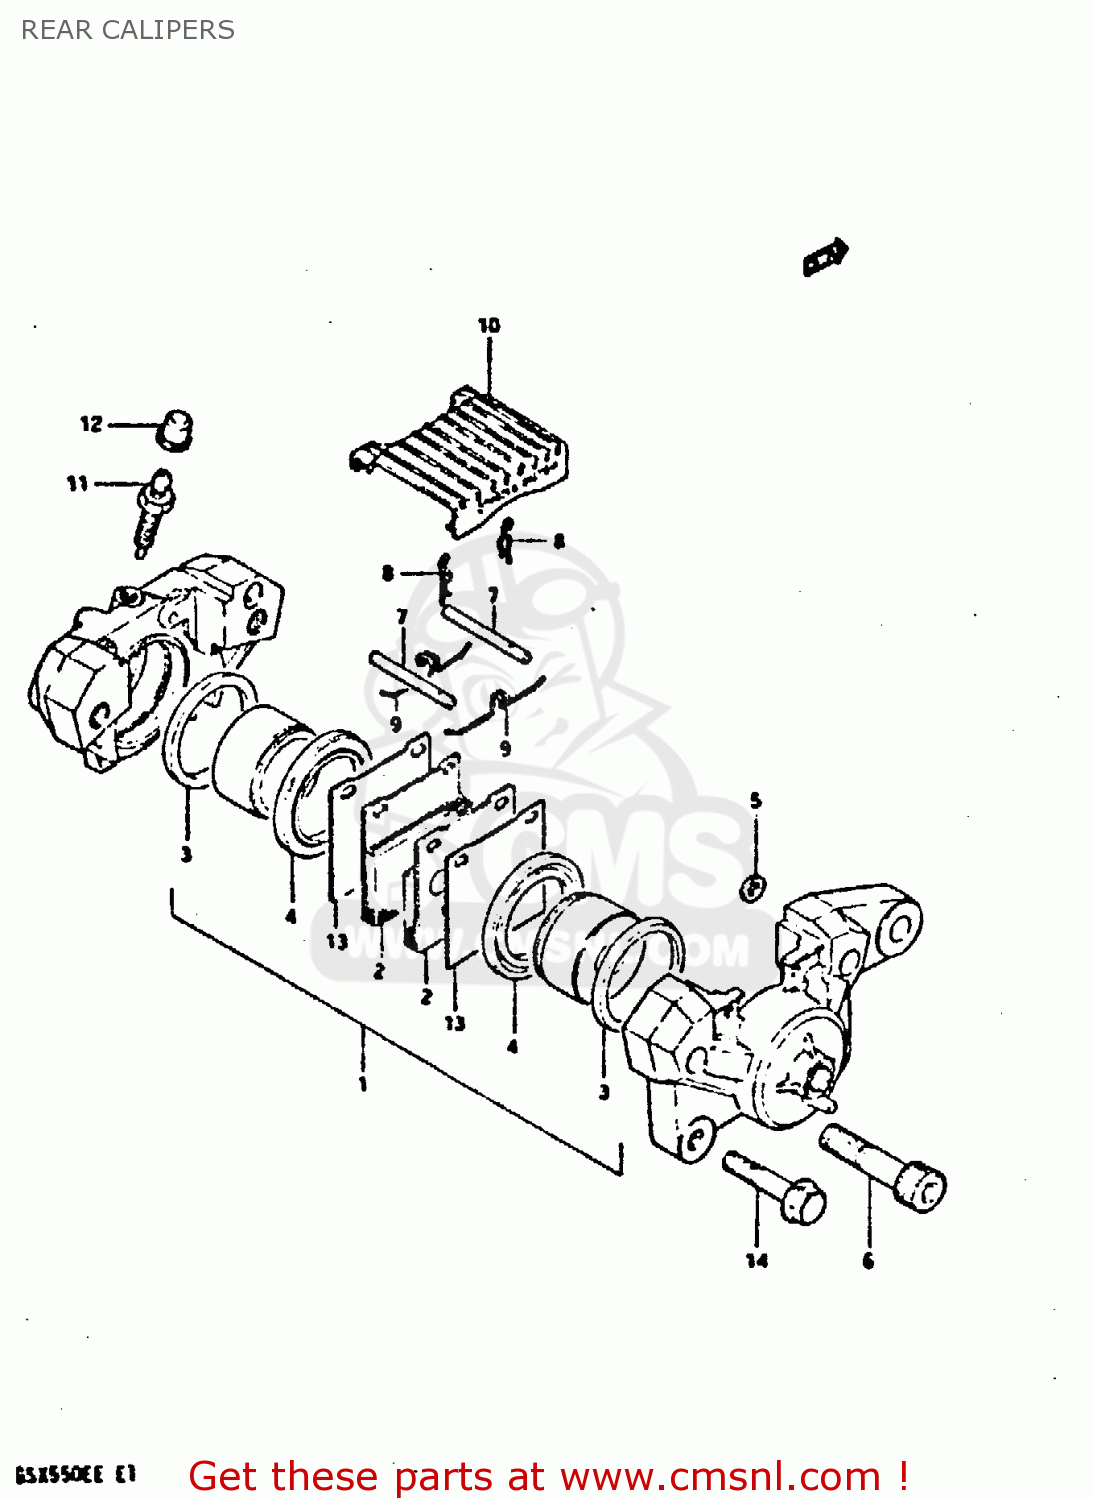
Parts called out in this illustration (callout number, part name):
1	PISTON SET
2	PAD (MCA)
3	SEAL,PISTON
4	BOOT
5	SEAL,JOINT
6	BOLT,CALIPER HOUSING
7	PIN,PAD
8	CLIP,PAD PIN
9	SPRING
10	COVER,CALIPER
11	BLEEDER
12	CAP,BREATHER
13	SHIM,PAD
14	BOLT
